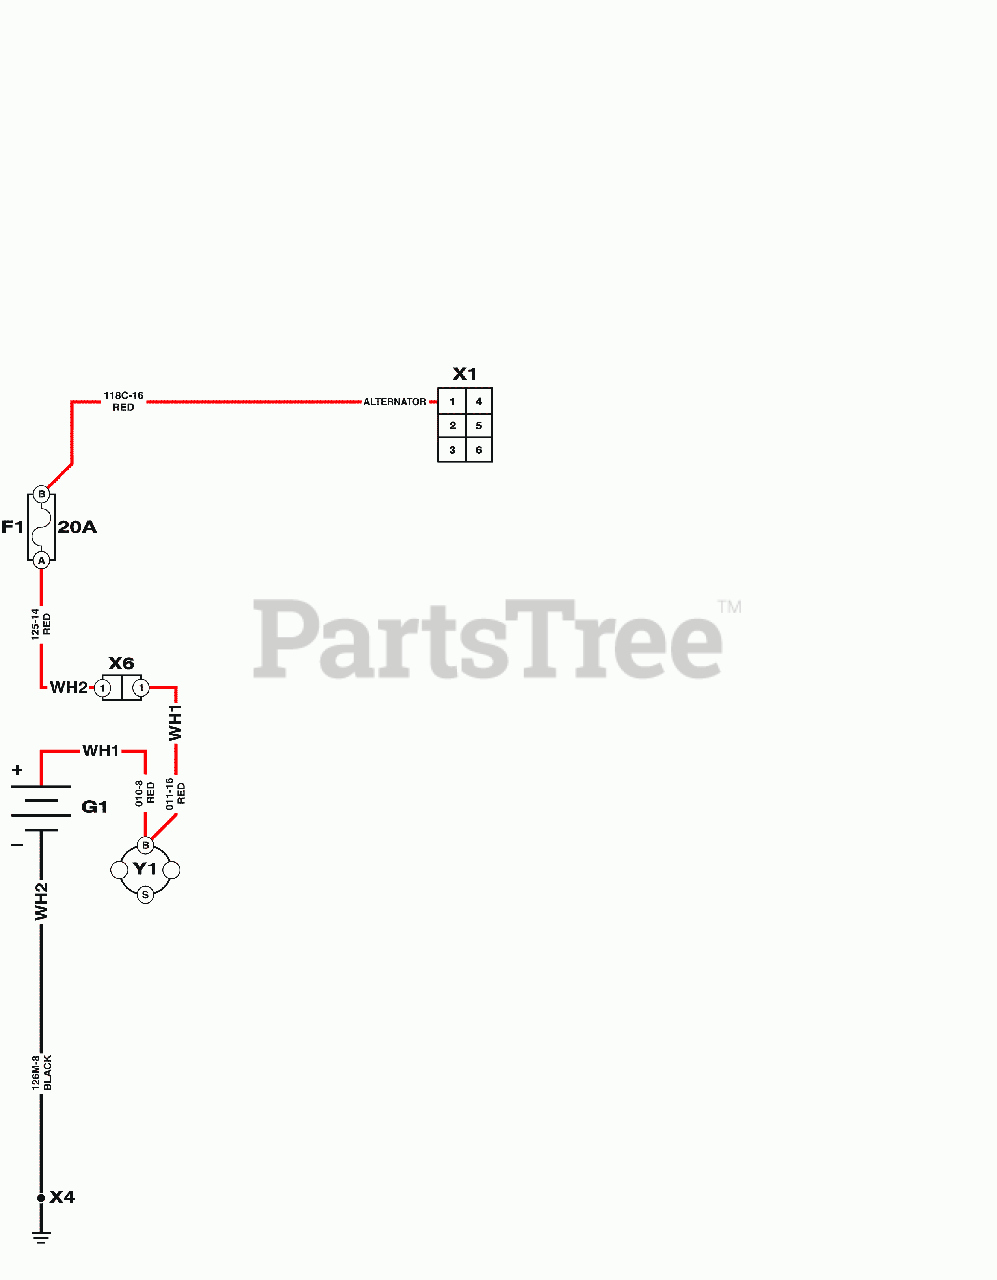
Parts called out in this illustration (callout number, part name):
F1	FUSE, Wiring Harness
G1	BATTERY, 12 Volt, 230 CCA
WH1	HARNESS, Battery, Solenoid
WH2	HARNESS, Main
X1	CONNECTOR, Engine
X4	CHASSIS GROUND POINT
X6	CONNECTOR, Battery Solenoid Harness to Main Harness
Y1	SOLENOID
